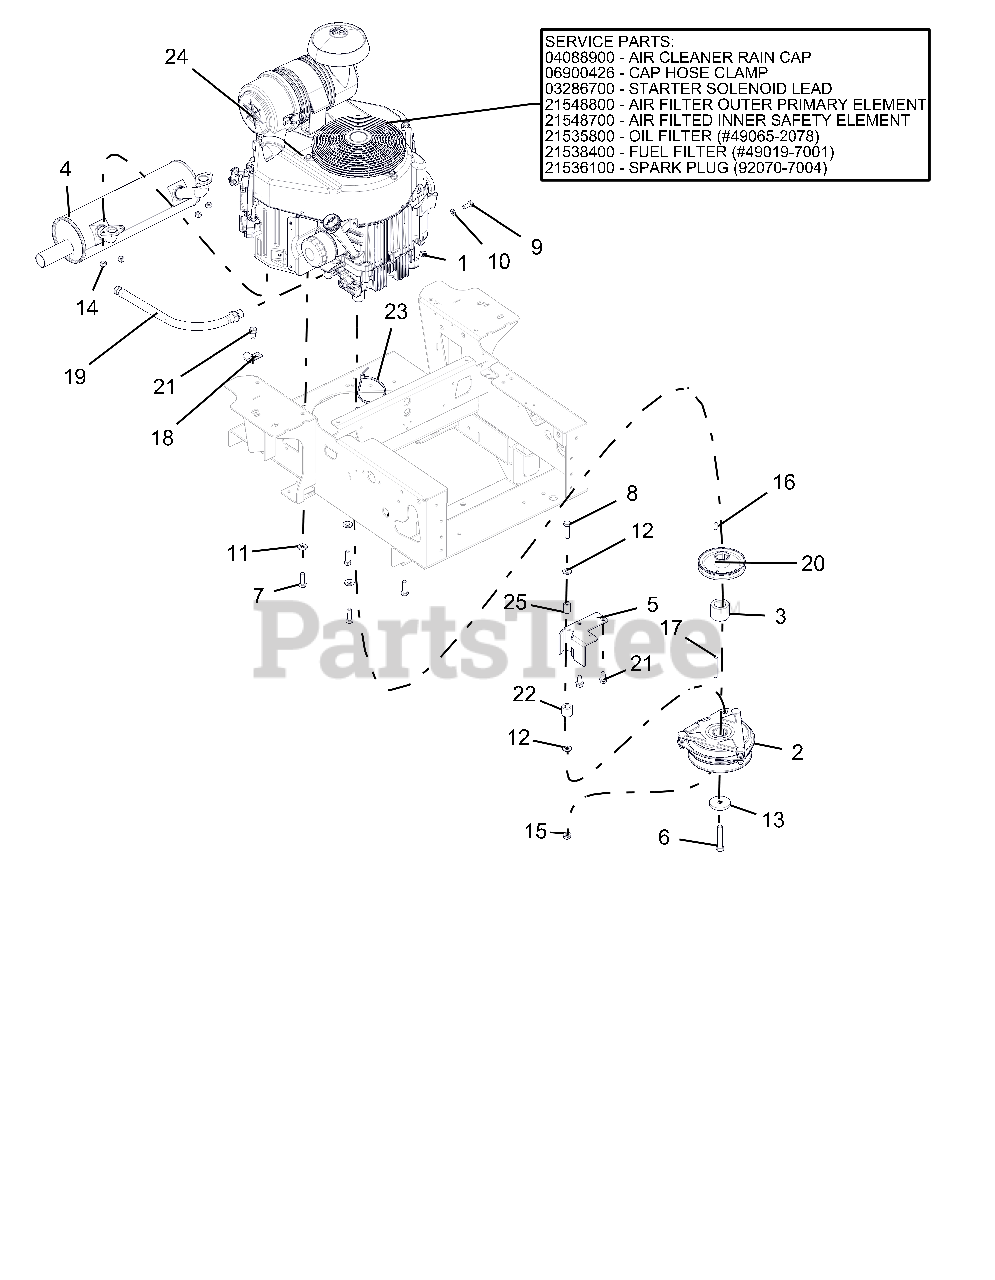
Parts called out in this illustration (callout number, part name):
1	CLAMP, FUEL LINE
2	CLUTCH, OGURA GT2.5-FE02
3	SPCR, 1.125 X 1.75 X 1.400
4	MUFFLER, KAWASAKI FX24/26 HP
5	BRKT, CLUTCH STOP
6	BLT-HEX .44-20X2.50 GR5 EP80 YWZC
7	BLT-HEX .38-16X1.25 GR5 YWZC NYTORQ
8	BLT-HEX .38-16X1.50 GR5 YWZC
9	@BLT-HEX M8-1.25X20 YWZC
10	WSHR-LK .31X.078 REG YWZC
11	WSHR, 3/8" SPRING DISC
12	WSHR-FL-STL.406X.812X.065 YWZ
13	WSHR-FL-STL .469X2.00X.25 YWZC
14	NUT-LK-TOP M8-1.25 YWZC
15	NUT, LK-TOP-FLG .38-16 YWZC
16	KEY-SQ .250X.250X.625
17	KEY, .25X.25X2.25
19	HOSE, OIL DRAIN
20	PULLEY, 4.50 OD X 1.127 ENGINE-BLACK
21	SCR-TAP .38-16X.75 HWH TR YWZ
22	BUMPER, RUBBER .62 X 1.0 X .88 LG
23	CABLE, TIE 5.50 LG
24	ENGINE, KAWASAKI FX691
24	AIR CLEANER RAIN CAP
24	CAP HOSE CLAMP
24	STARTER SOLENOID LEAD
24	AIR FILTER OUTER PRIMARY ELEMENT
24	AIR FILTER INNER SAFETY ELEMENT
24	OIL FILTER (#49065-2078)
24	FUEL FILTER (#49019-7001)
24	SPARK PLUG (#92070-7004)
25	BUSH.,S.391X.622X.95 ST REV A
